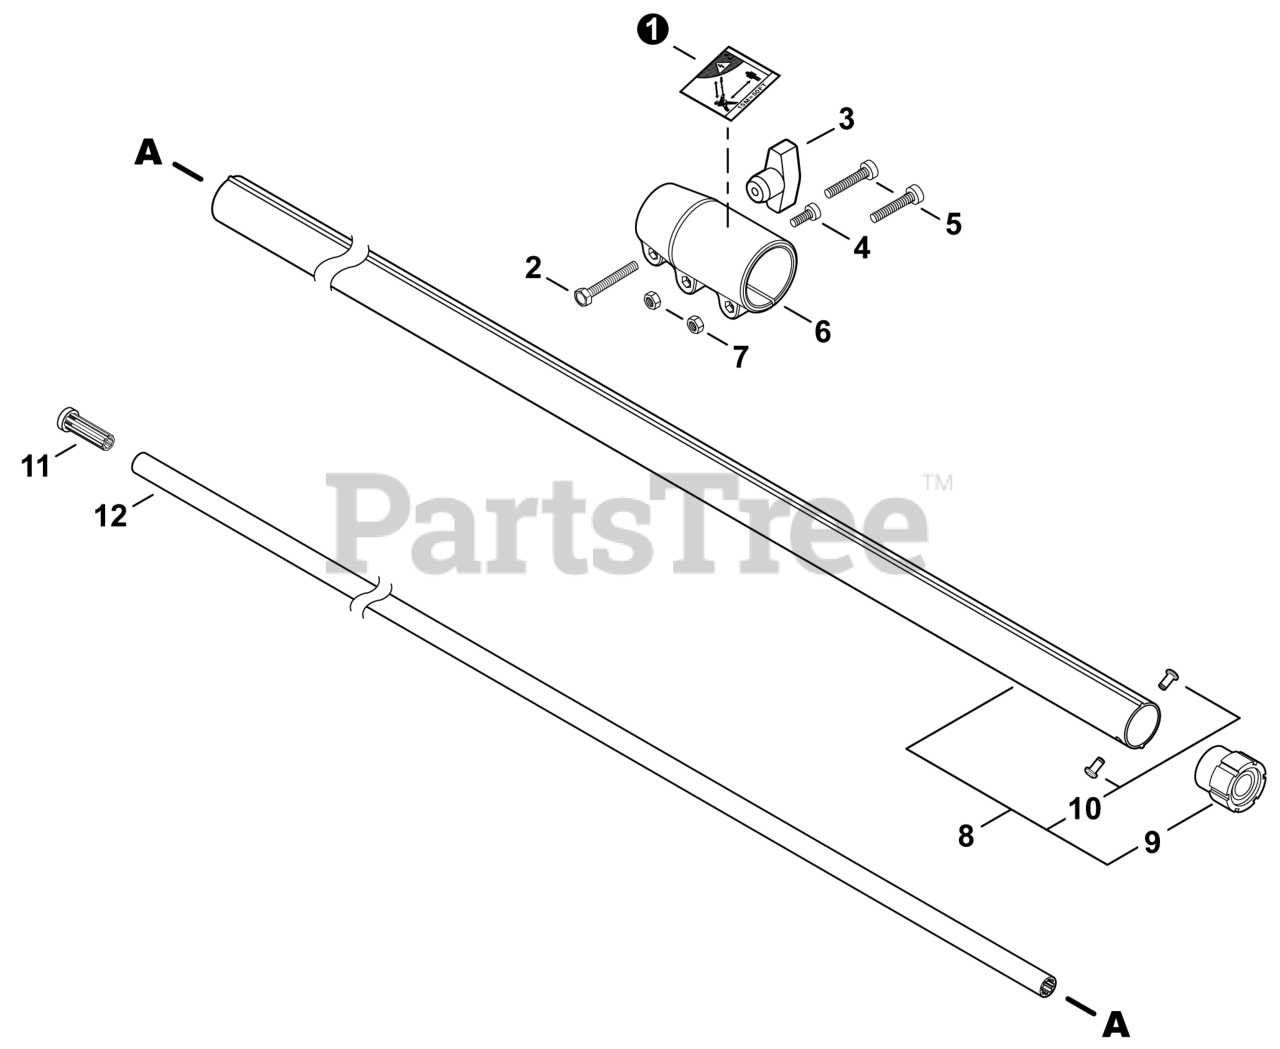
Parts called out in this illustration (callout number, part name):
1	LABEL - CAUTION
2	BOLT 6x25
3	THUMBSCREW
4	BOLT, TORX 5x12
5	BOLT, TORX 5x20
6	COUPLING, MAIN PIPE
8	MAIN PIPE ASSY - BLACK
9	HOLDER ASSY, BEARING
12	DRIVESHAFT - UPPER
